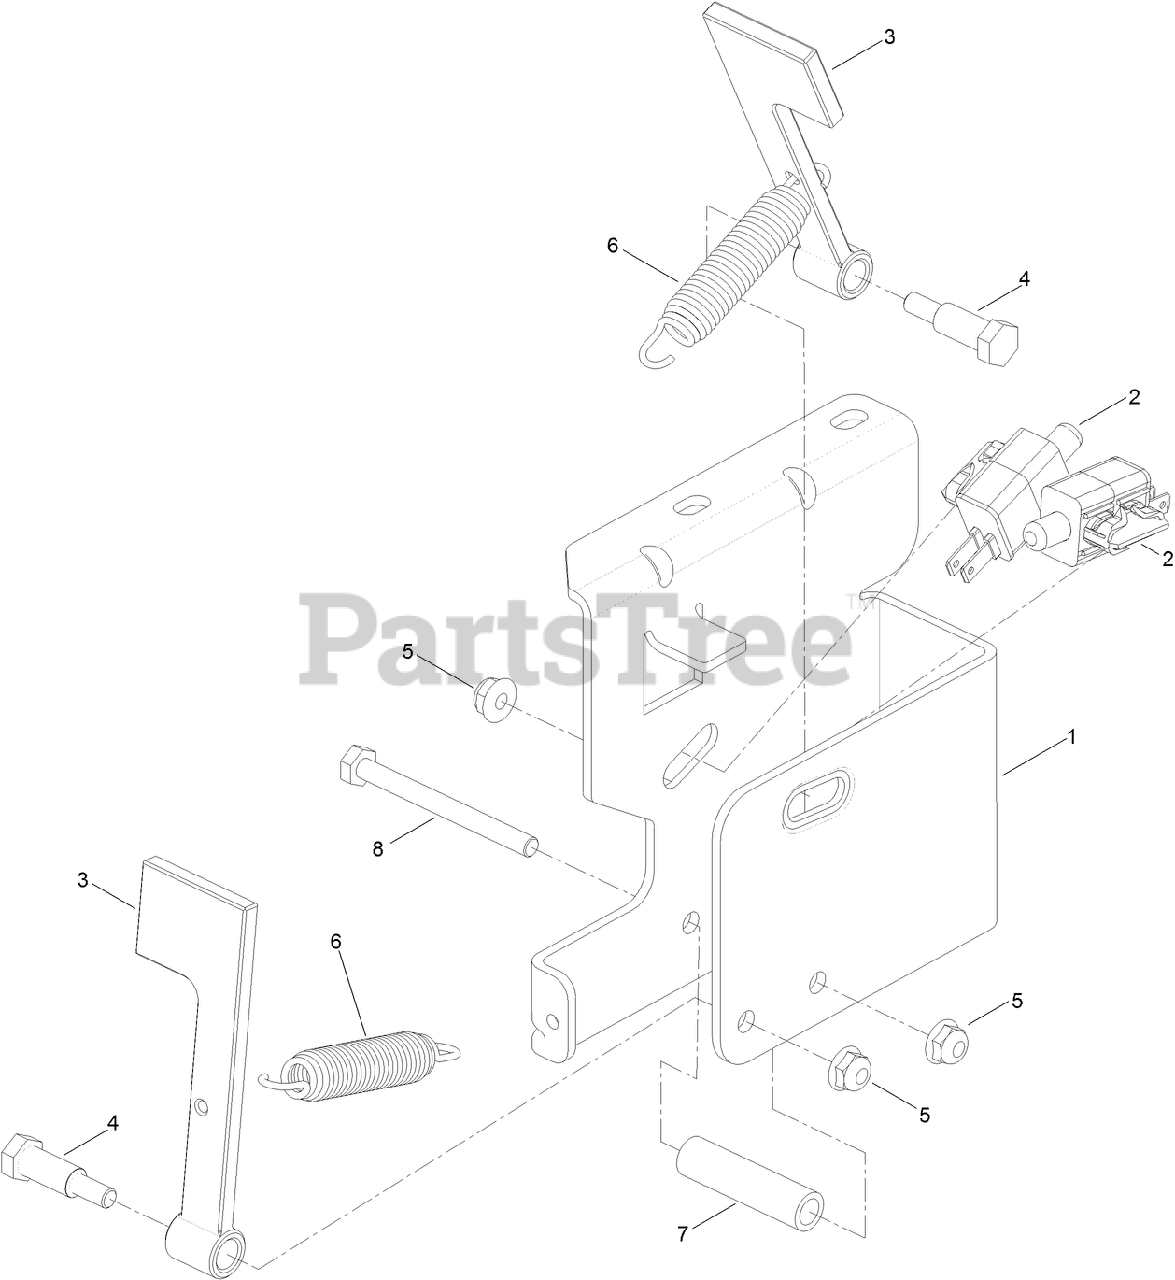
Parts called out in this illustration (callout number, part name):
1	BRACKET-SWITCH
2	SWITCH
3	ARM-SWITCH
4	BOLT-SHOULDER
5	NUT-HF
6	SPRING-EXTENSION
7	SPACER
8	SCREW-HH
